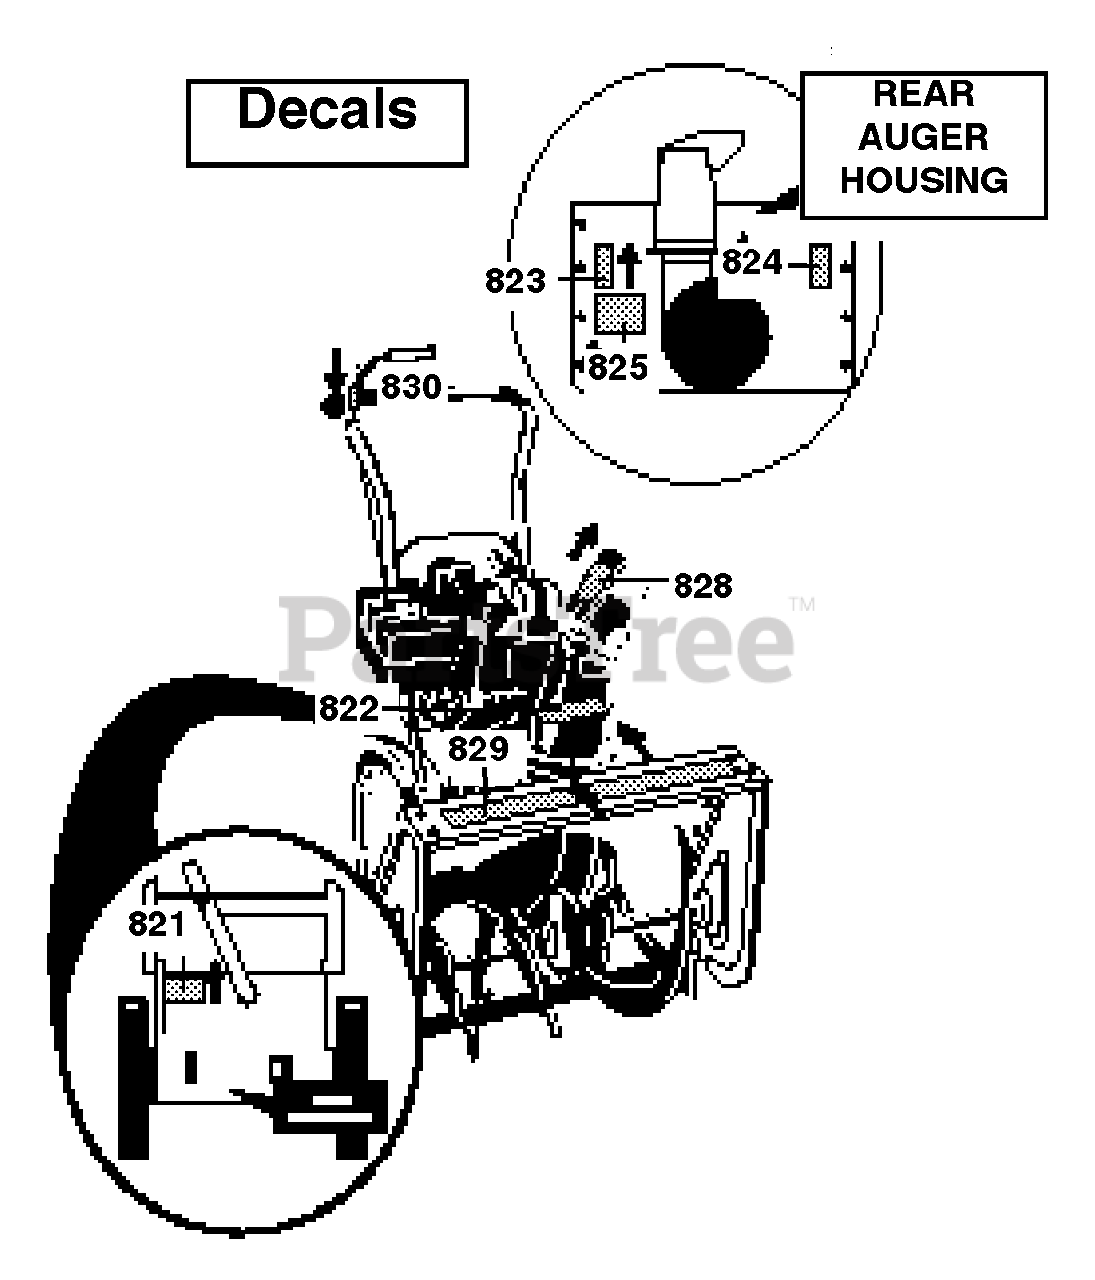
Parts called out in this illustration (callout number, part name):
822	Decal, 9" Impeller
823	Decal, Danger Chute
824	Decal, Danger Auger Foot
825	Decal, Danger English
828	Decal, Husq. Crown
829	Decal, ST522H
830	Decal, Auger Drive Engage
